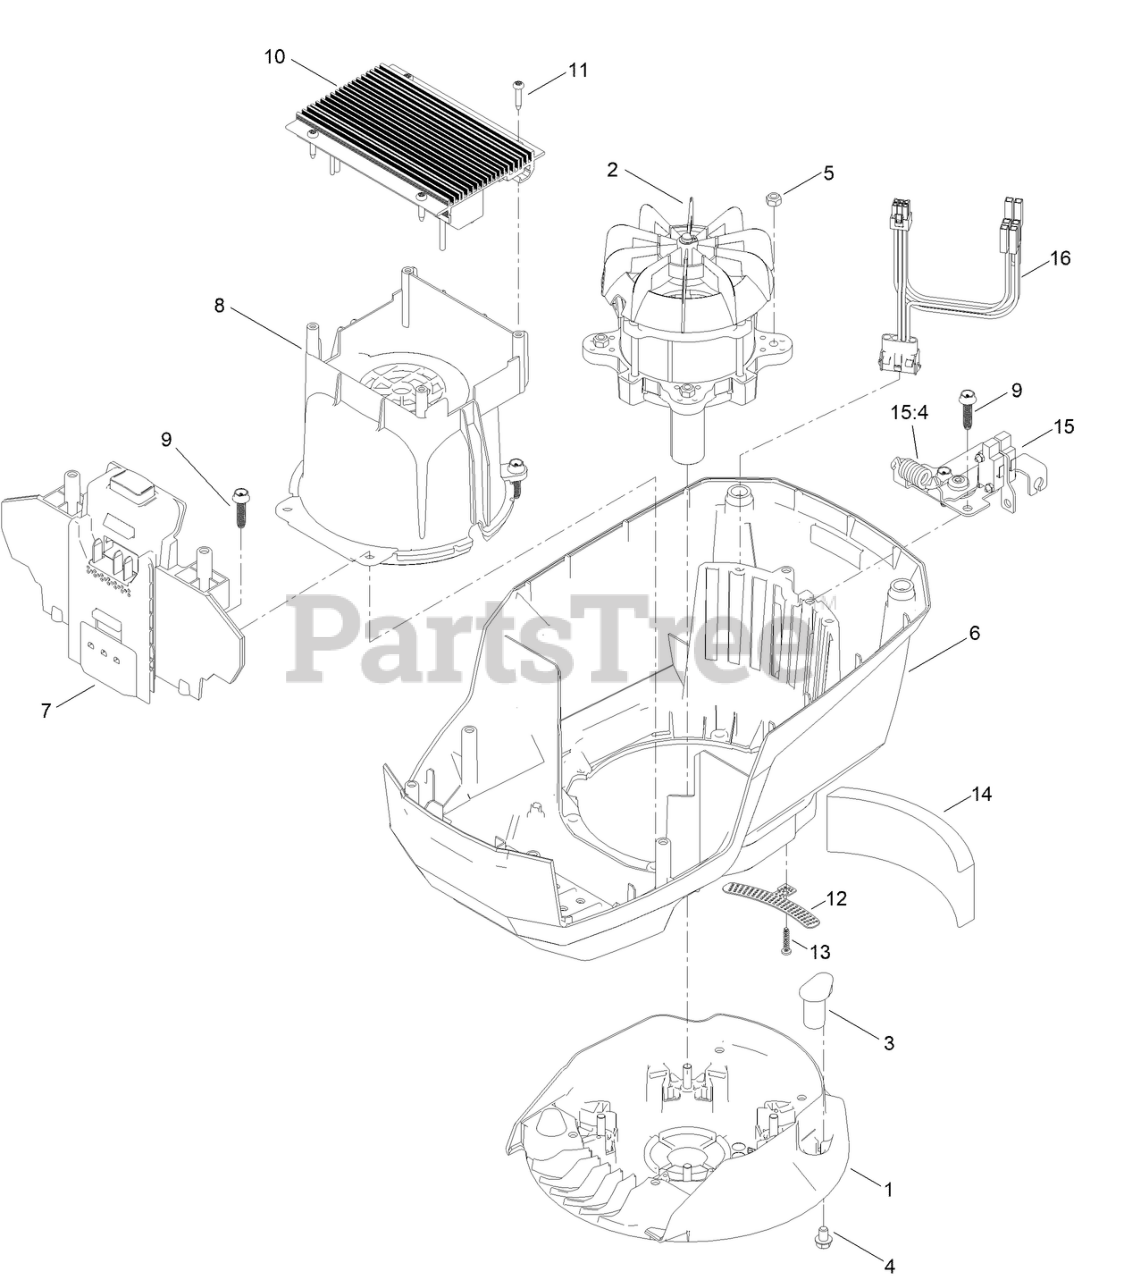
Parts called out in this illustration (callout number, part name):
1	BASE-MOUNT, MOTOR
2	MOTOR-2KW
3	INSERT-MOUNT, MOTOR
5	NUT-LOCK
6	SHROUD-LOWER
7	BATTERY RECIEVER ASM
8	SHROUD-MOTOR
9	SCREW-FLANGE, PLASTIC
10	CONTROLLER-MOTOR
12	BRACKET-FOAM
13	SCREW-PLASTIC, PPH
15	BAIL SWITCH ASM
15:4	SPRING-EXTENSION
16	HARNESS-WIRE
